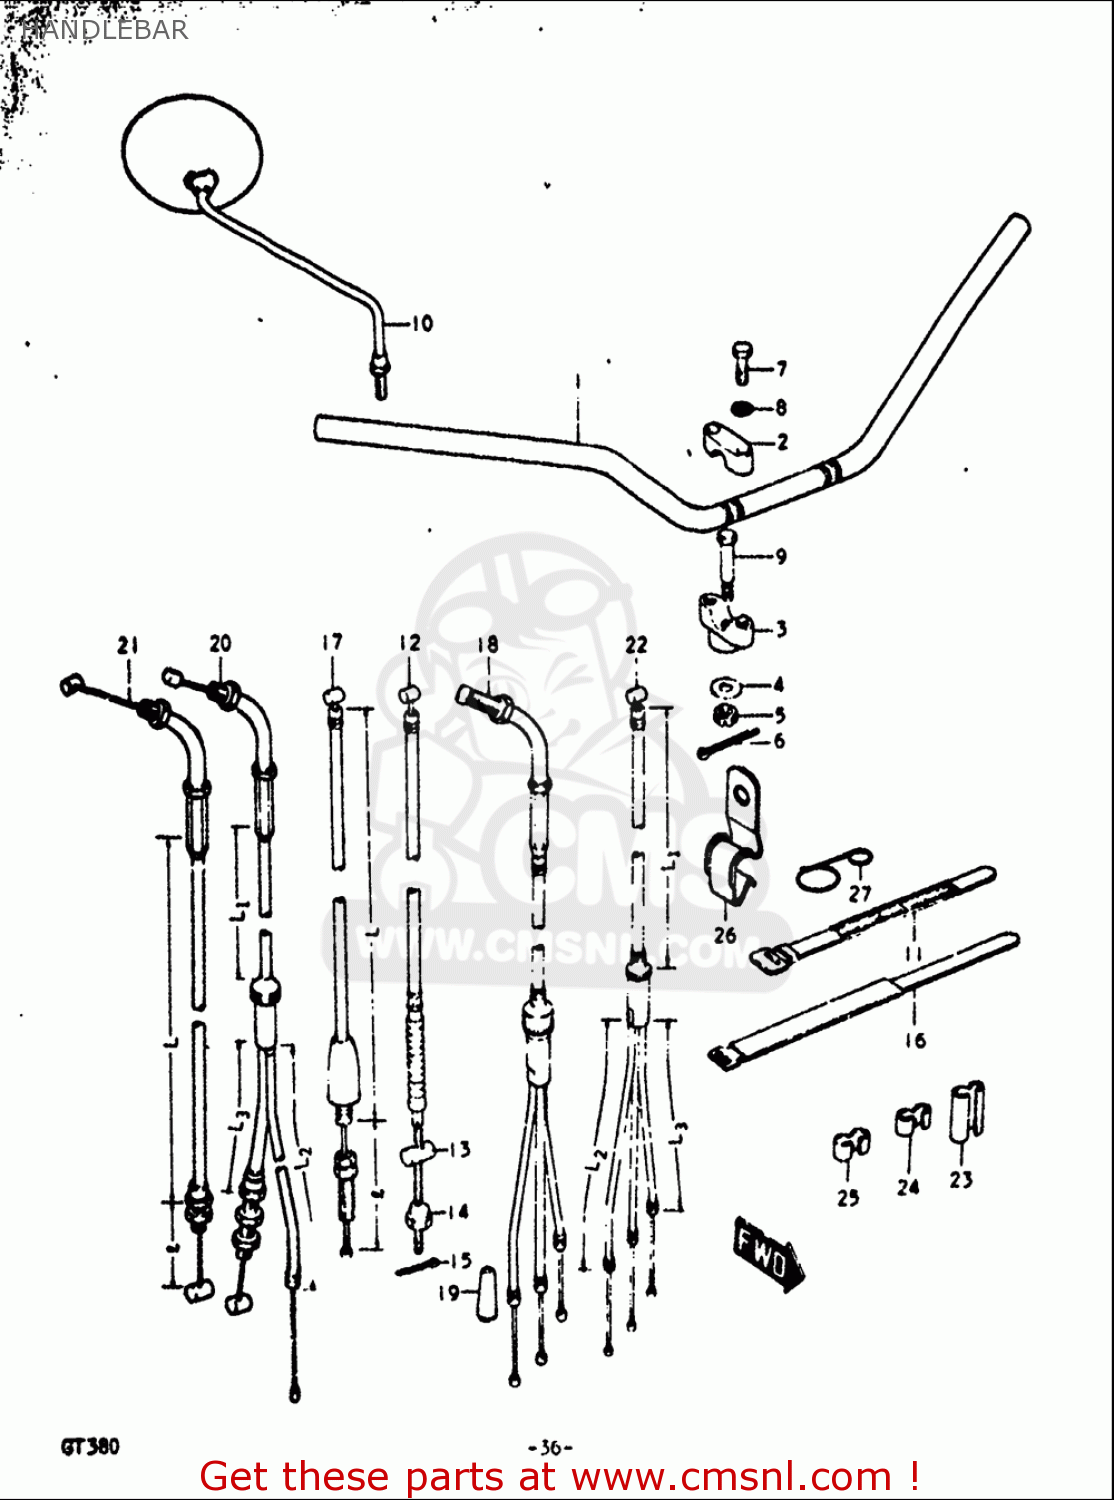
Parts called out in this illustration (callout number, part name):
1	HANDLEBAR
2	HOLDER,HANDLE UPR
3	HOLDER,HANDLEBAR LWR
4	WASHER(10.5X28X2.3)
5	NUT
6	PIN, COTTER
8	WASHER,LOCK
10	MIRROR ASSY,RE
11	CLAMP(L:120)
12	CABLE,FR BRAKE
13	PIN(13X18)
14	NUT
15	PIN
16	CLAMP(L:250)
17	WIRE,CLUTCH
18	CABLE ASSY,THROTTLE
19	SEAL,DUST(7X18X30)
21	CLIP
22	CLIP
23	CLIP
24	GUIDE,CABLE
